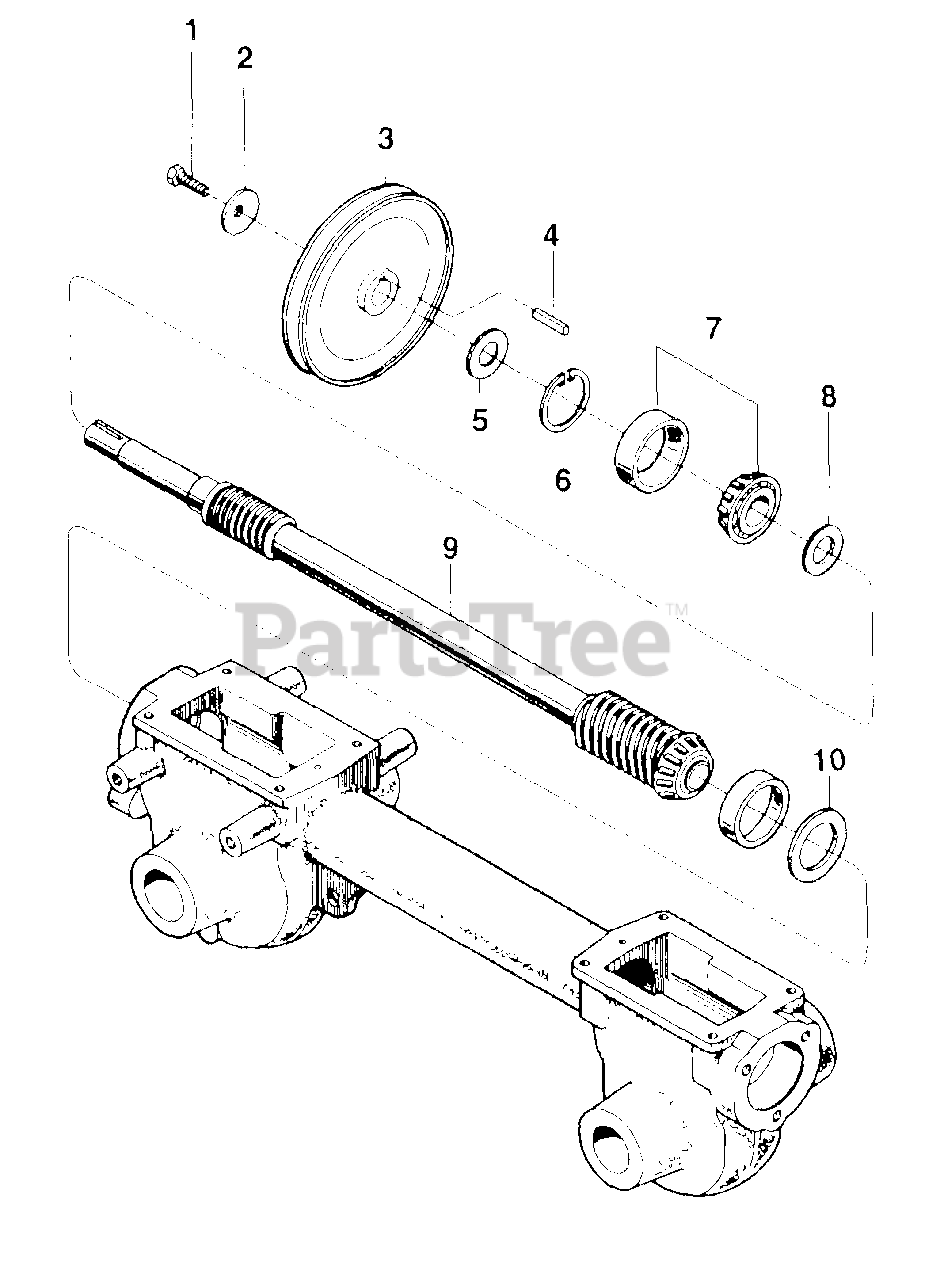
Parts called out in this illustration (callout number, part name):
1	Bolt-Hex Head, 5/16-24 x 3" Grade 5
2	Washer-Belleville
3	Pulley-Transmission
4	Key-Transmission Pulley, 3/16 x 1
5	Support Washer-Front
6	Snap Ring
7	Bearing-Tapered Roller with race
8	Support Washer-Rear
9	Driveshaft Assembly
10	Shim-Rear Bearing Cap, .010 thick
